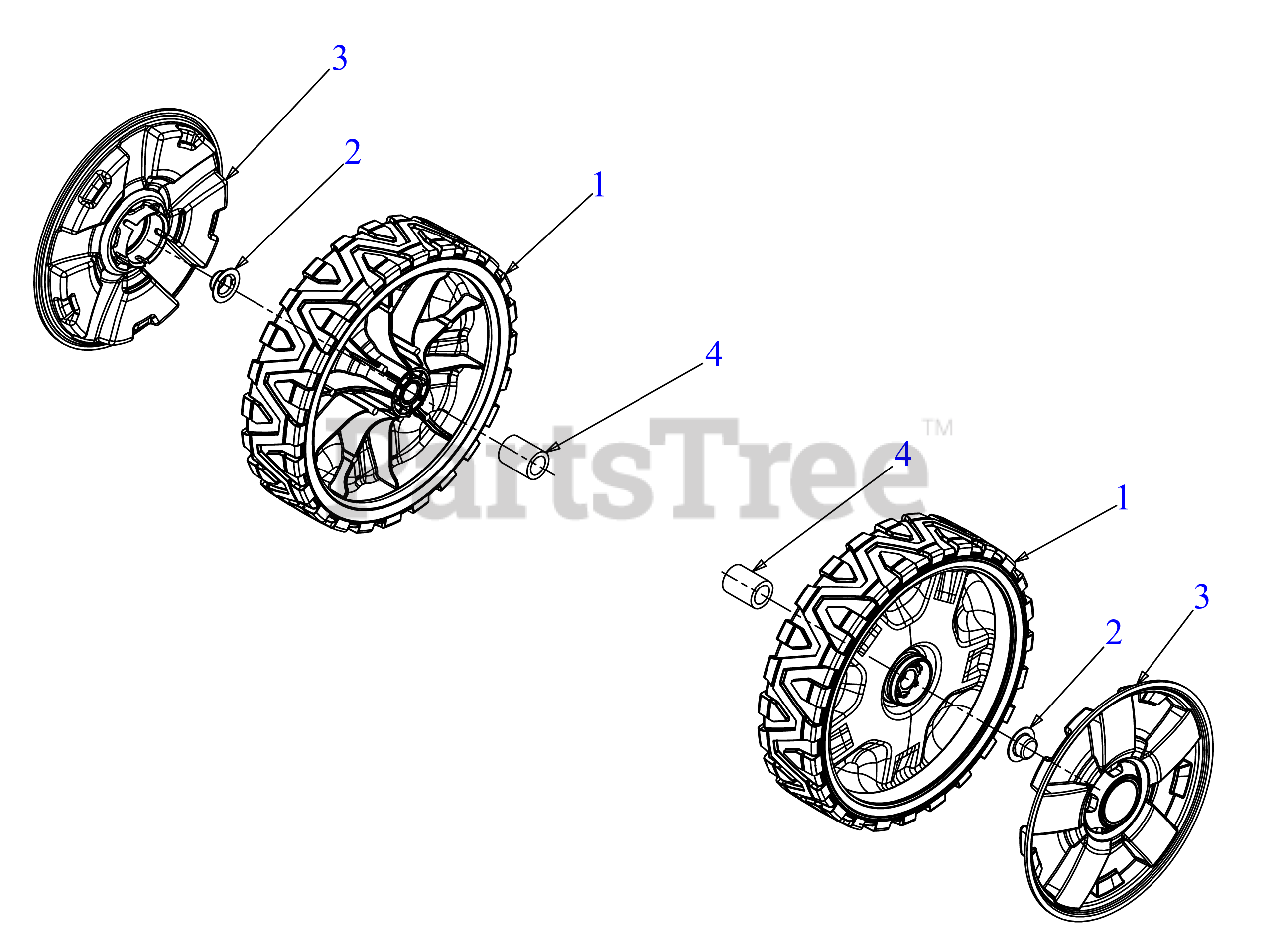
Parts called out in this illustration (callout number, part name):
1	WHEEL ASSEMBLY (8 x 2)
2	PUSH CAP
3	8" HUBCAP (SBD GRAY)
4	SPACER .525 x .775 x 1.015
